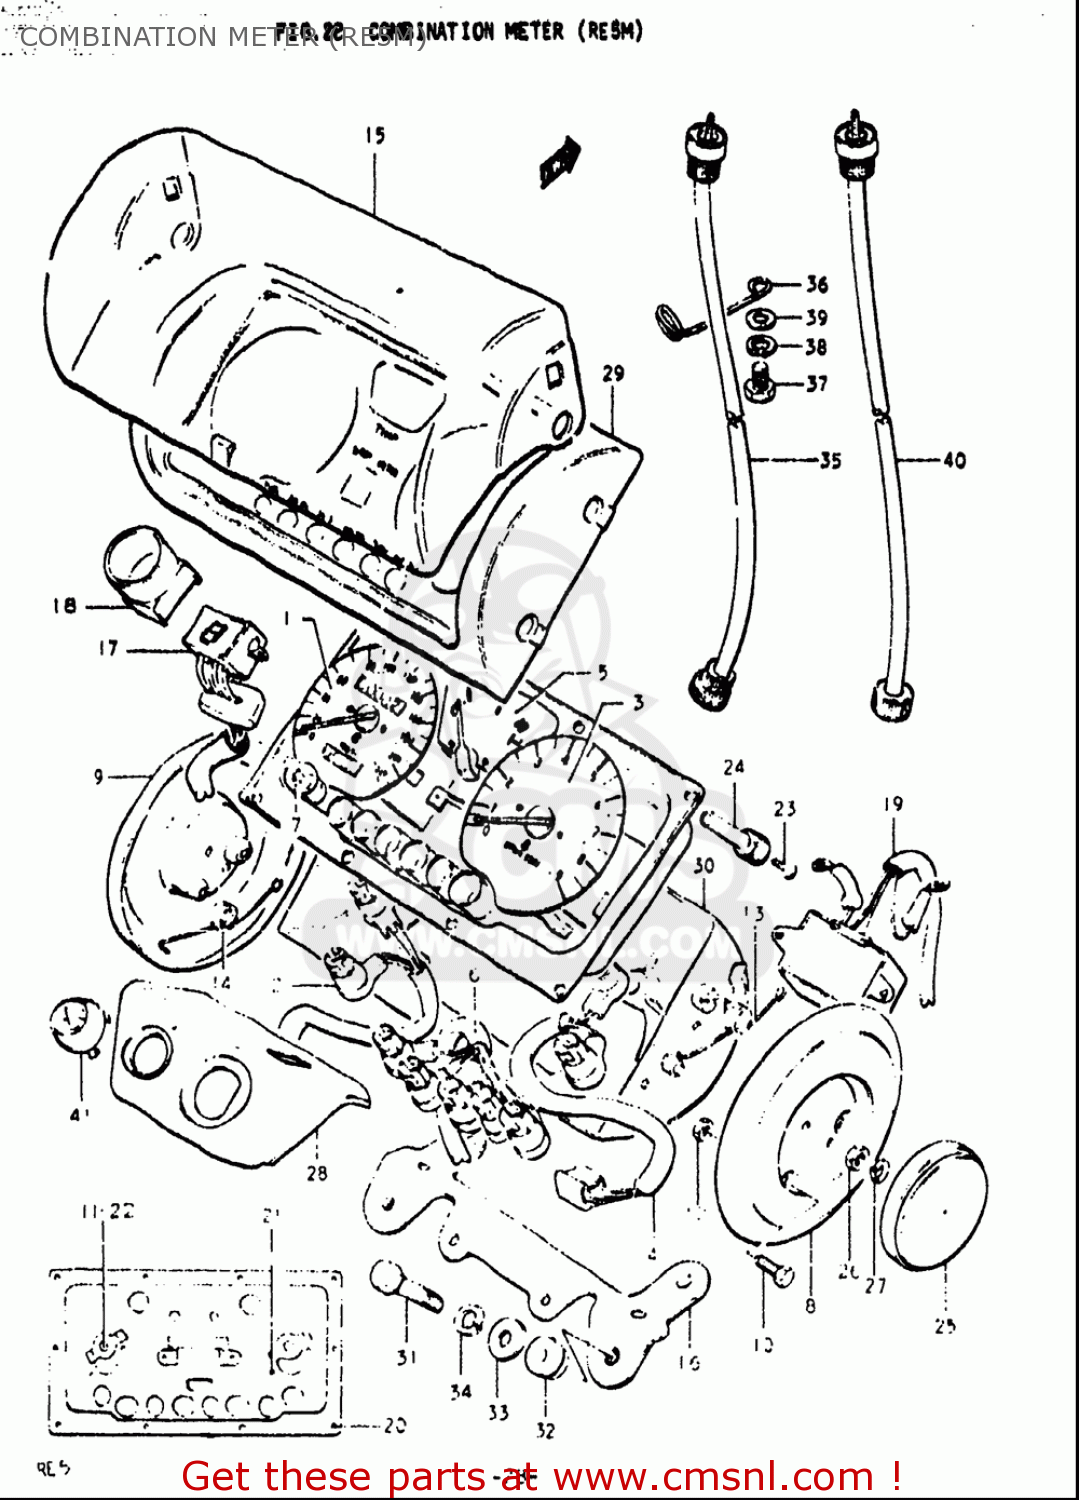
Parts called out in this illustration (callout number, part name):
7	BULB(12V3.4W,STANLEY,A72A)
10	BOLT
11	WASHER,LOCK
12	NUT
20	SCREW
21	SCREW 4X6
22	SCREW
23	SCREW(2X6)
25	REFLEX REFLECTOR,RR
26	NUT
27	WASHER,LOCK
32	CUSHION,METER BRACKET
34	WASHER,LOCK
36	GUIDE,SPEEDOMETER CABLE
37	BOLT
38	WASHER,LOCK
39	WASHER
41	CAP,SPEED WARNER LAMP HOLE
